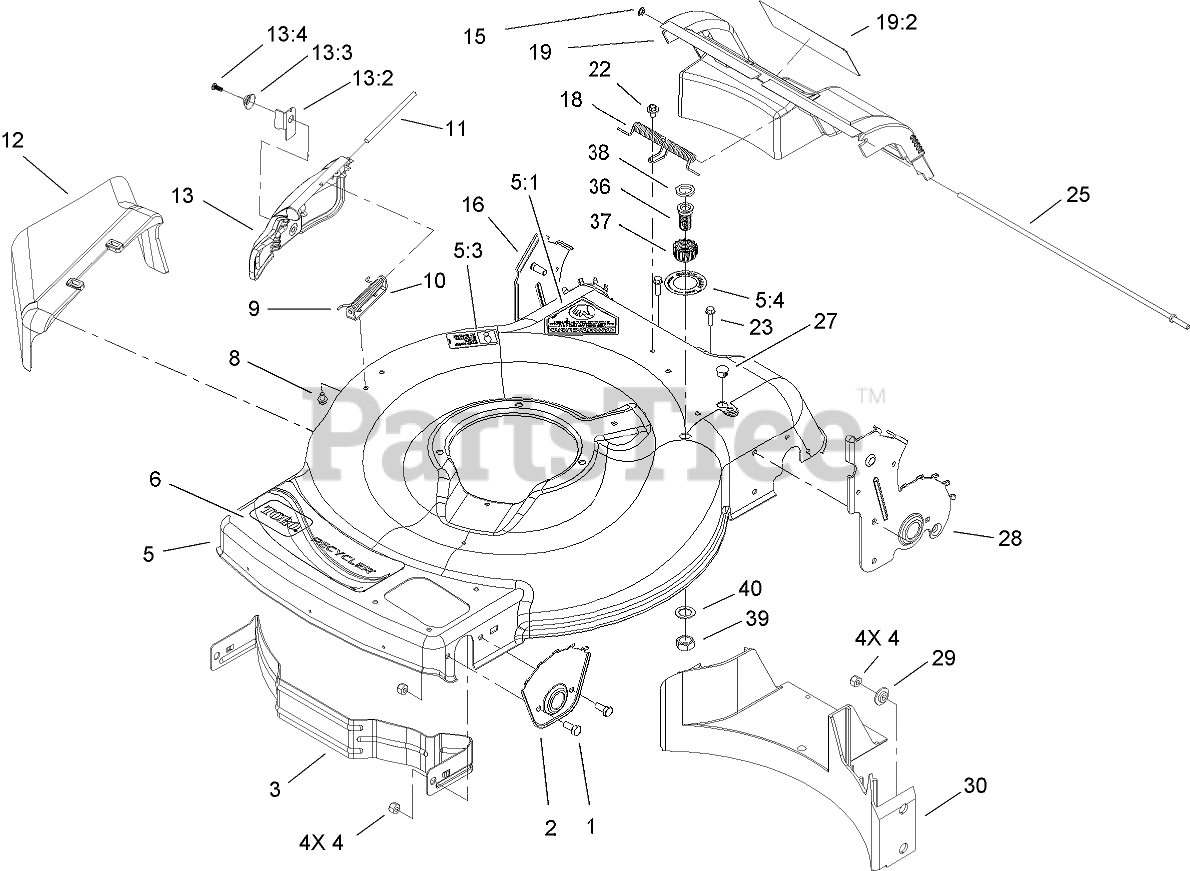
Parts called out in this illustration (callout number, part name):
1	SCREW-HH
2	Plate-HOC, Front
3	Baffle-Front
4	NUT-LOCK, NI
5	BBC HOUSING ASM
5:1	DECAL-DANGER
5:3	DECAL-PLACEMENT, FOOT
5:4	DECAL-PORT, WASHOUT
6	DECAL-RECYCLER (RWD)
8	SCREW-HWH
9	SPRING-TORSION
10	BRACKET-COVER
11	ROD-COVER
12	CHUTE-DISCHARGE, SIDE
13	DISCHARGE DOOR ASM
13:2	LATCH-DOOR
13:3	CAP-DOOR
13:4	SCREW-PLASTITE
15	NUT-PUSH
16	8 INCH RH HOC PLATE ASM
18	Spring-Door, Rear
19	REAR DOOR ASM
19:2	DECAL-WARNING
22	SCREW AND WASHER ASM
23	SCREW-HWH
25	Rod-Pivot, Rear Door
27	Plug-Dome
28	8 INCH LH HOC PLATE ASM
29	Washer-Stepped
30	Baffle-Rear
36	PORT-WASHOUT
37	COUPLING-HOSE, WASHOUT PORT
38	WASHER-SEAL, WASHOUT PORT
39	NUT-JAM
40	WASHER-TOOTH, INTERNAL
